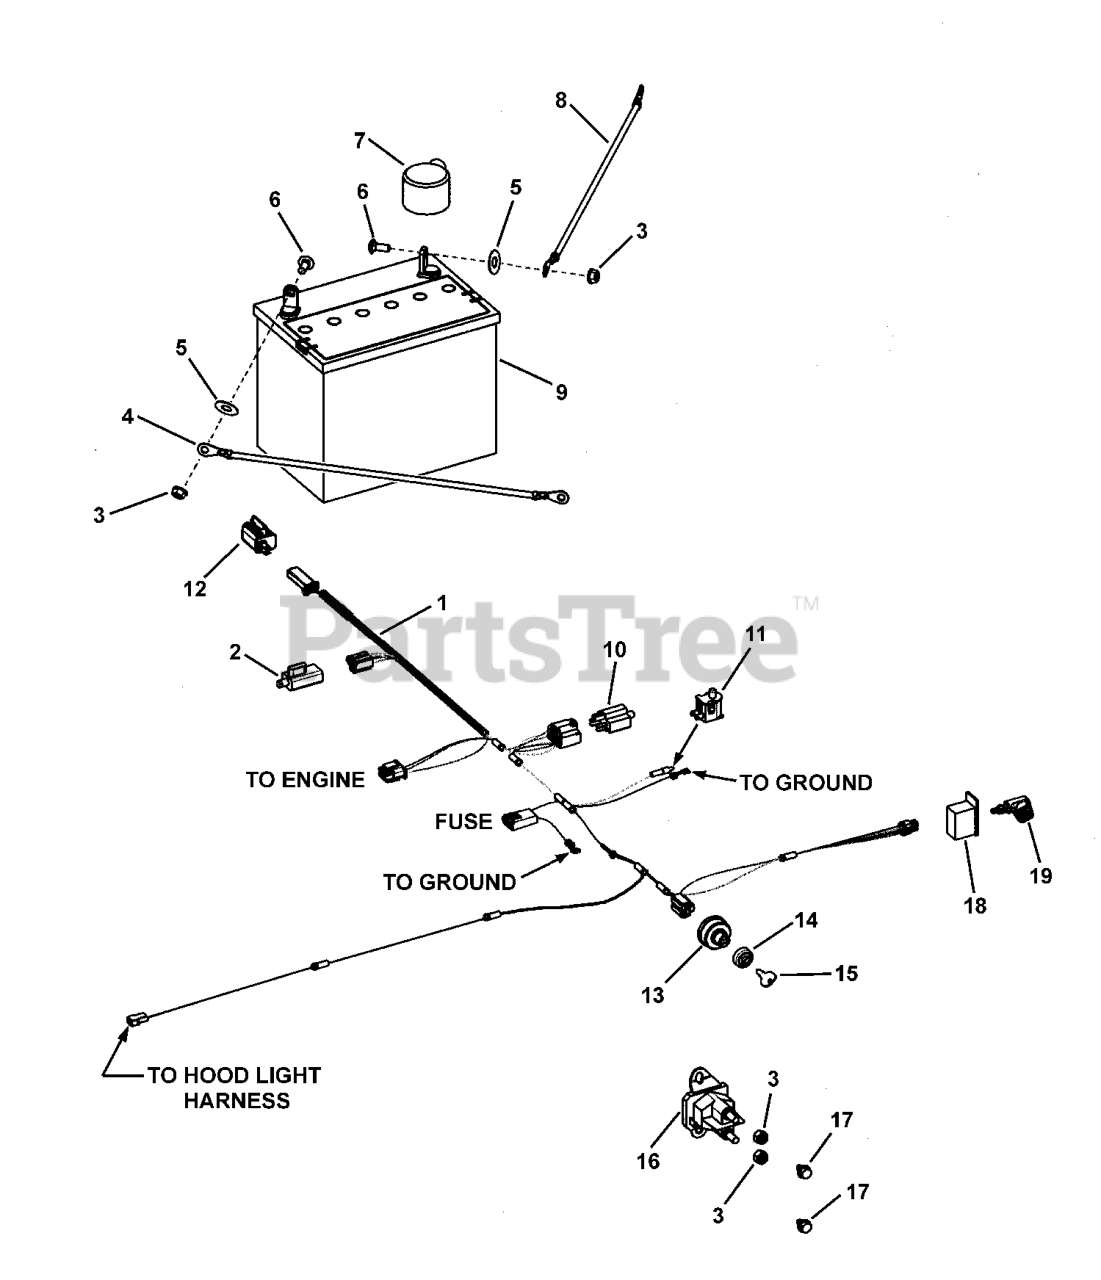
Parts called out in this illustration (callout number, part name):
1	HARNESS, WIRING, HYDRO TCT, MAN PTO
2	SWITCH, LIMIT, NO/NC, SNAP-IN
3	NUT-HEX 1/4-20 NC-2B YELLOW
4	CABLE-BAT 8GA 12.00L - BLACK
5	LOCKHER, 1/4
6	CAPSCREW-HEX HD 1/4-20X0.750 G5 YEL
7	BOOT BATTERY POSITIVE
8	CABLE-BAT 8GA 18.00L - RED
9	BATTERY, 12 VOLT, 230 CCA
10	SWITCH, 3 POLE, PLUNGER, SNAP-IN
11	SWITCH, Seat, Push Button (NC)
12	SWITCH, LIMIT, NO, SNAP-IN
13	SWITCH,IGNITION-AFTERFIRE SOLENOID
14	CAP-IGNITION SWITCH
15	KEY, IGNITION
16	SOLENOID - 3 POLE
17	SCREW 1/4-14X.38"ST-
18	SWITCH, RMO Module Only
19	KEY, RMO Module Plastic
